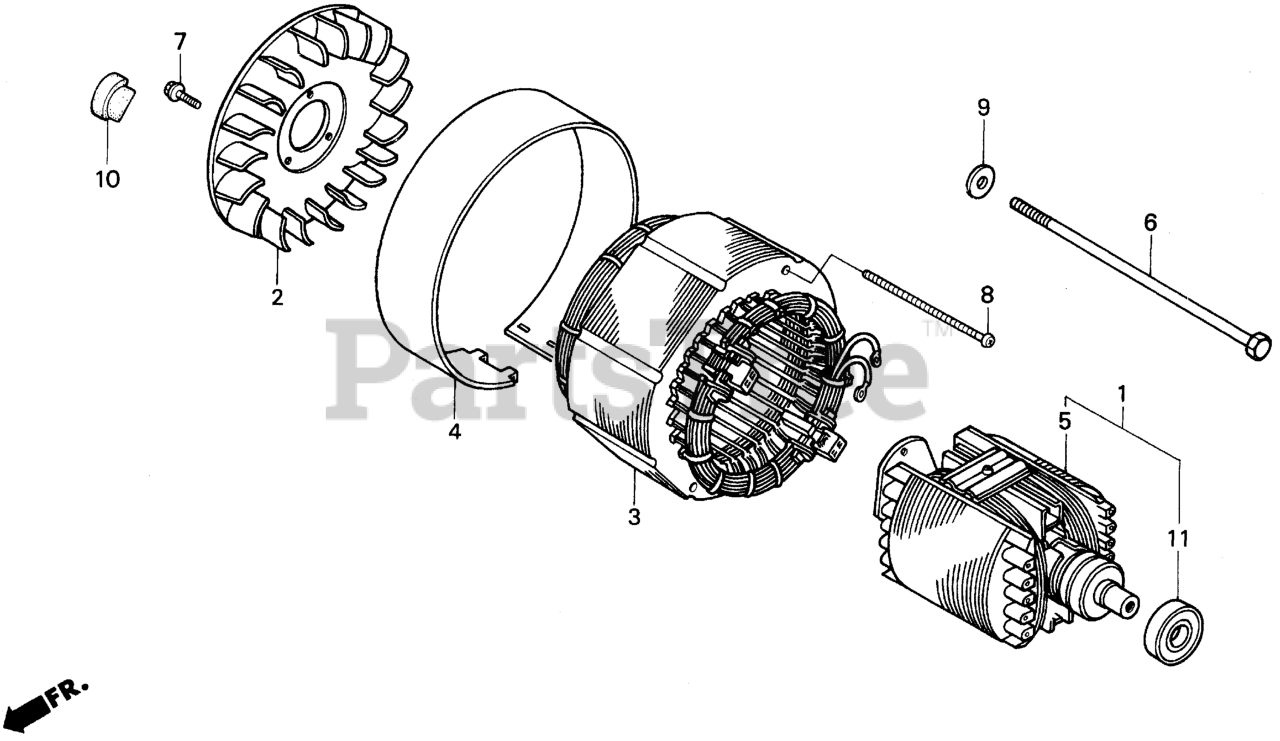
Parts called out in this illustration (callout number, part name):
1	ROTOR
2	FAN, GENERATOR COOLING
3	STATOR ASSY.
4	COVER, STATOR
5	ROTOR
6	BOLT, HEX. (10X250)
7	SCREW, TAPPING (5X14)
8	BOLT-WASHER (5X195)
9	WASHER (10.5MM)
10	GROMMET, CRANKCASE
11	BEARING ASSY. (6204)
11	BEARING, RADIAL BALL (6204UU)
